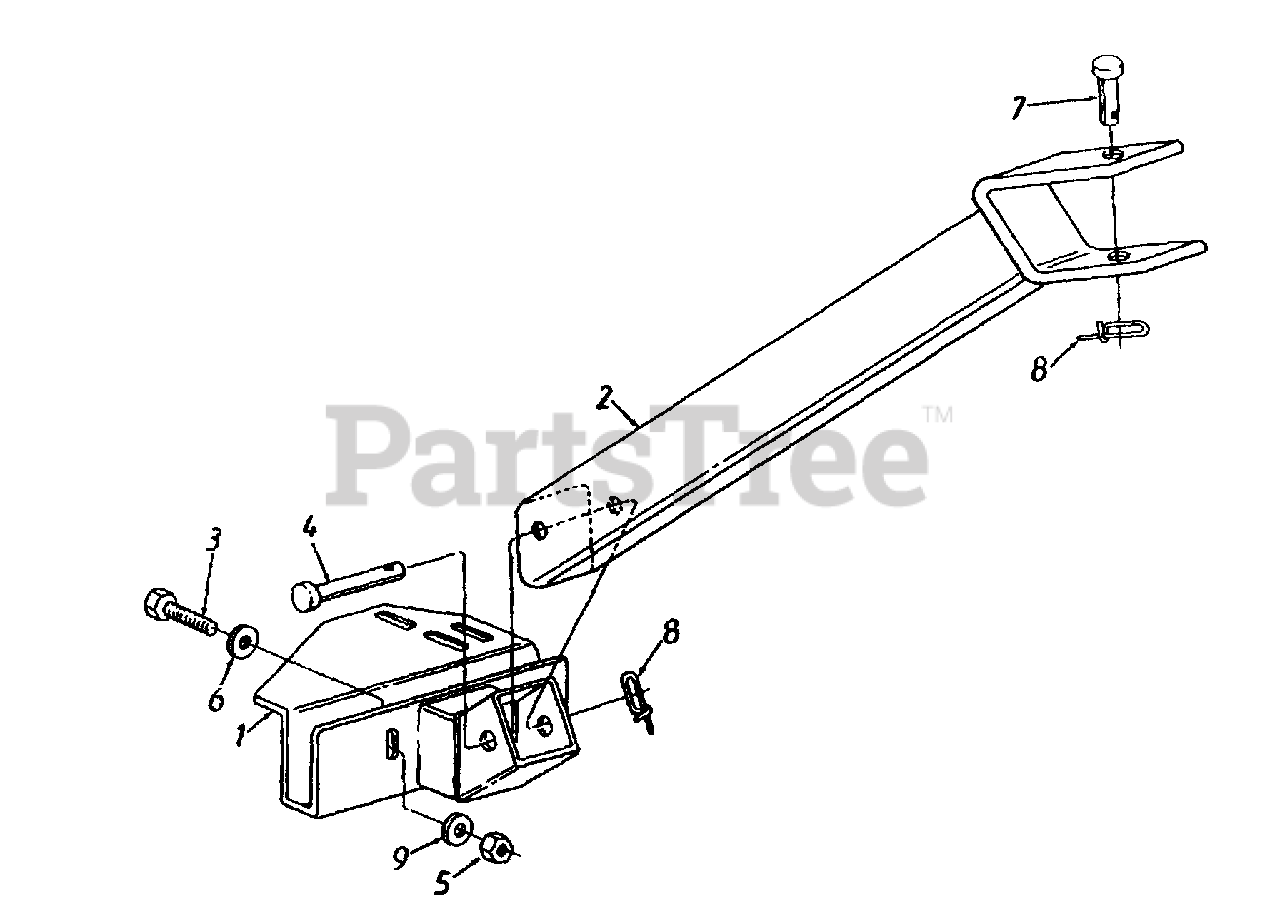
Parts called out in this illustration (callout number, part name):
4	Clevis Pin 2.4" Lg.
5	Hex Nut 3/8-16 Thd.
6	Fl-Wash..406" I.D. x 1.25" O.D. x .10"
7	Clevis Pin 4.62" Lg.
8	Spring Pin
9	L-Wash. 3/8" I.D.
